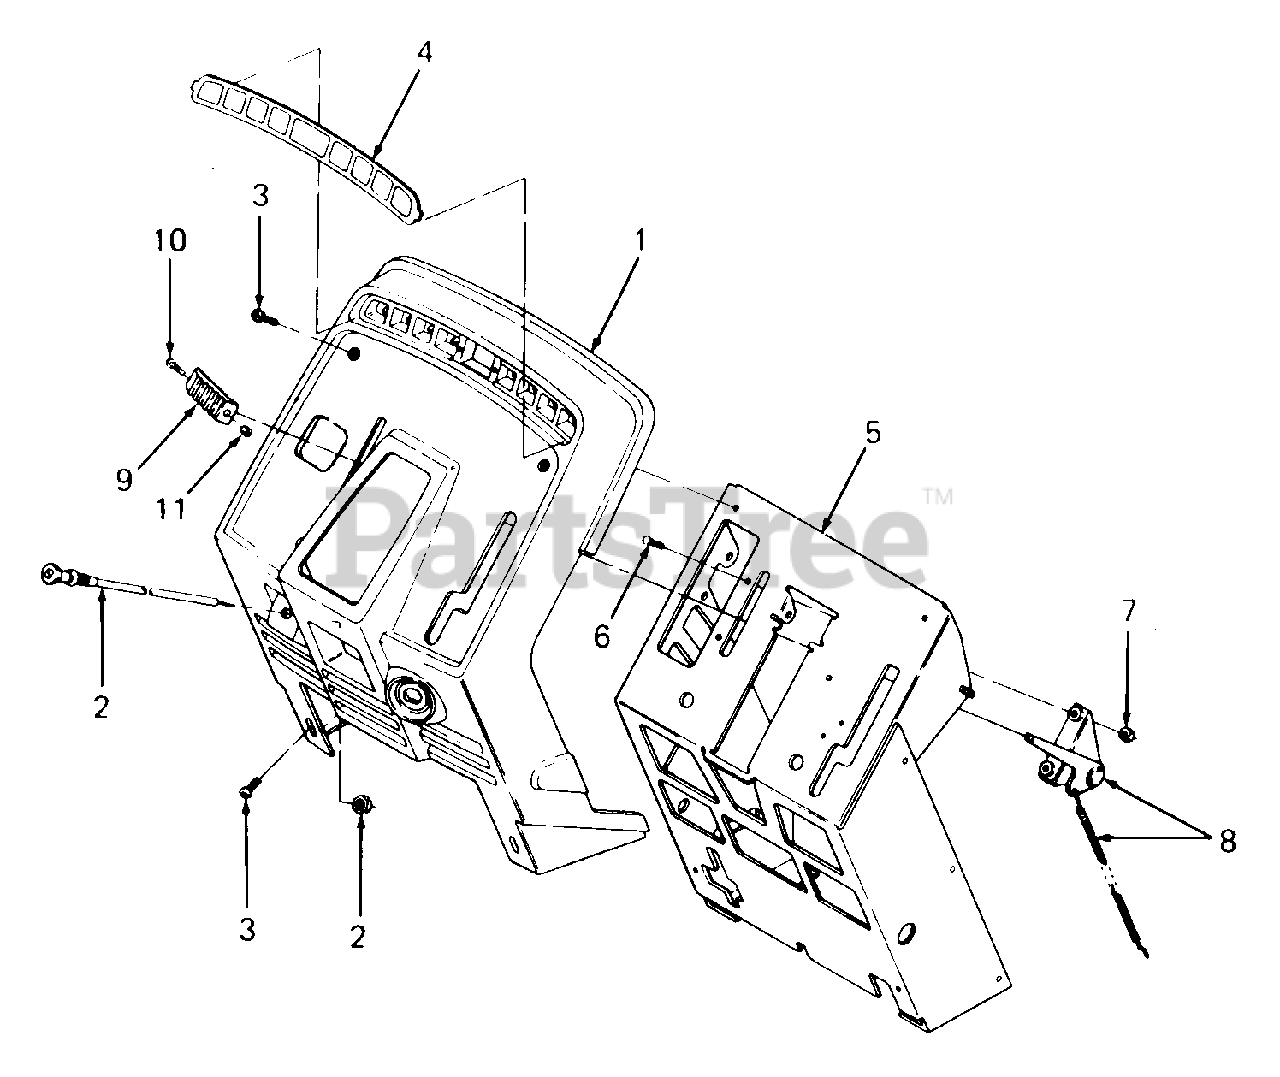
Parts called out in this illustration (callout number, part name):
1	Panel, Instrument
2	Choke Cable w/Nut
3	Screw, Pan Hd Cutting, #10-24 x .75 Lg
4	Label, Dash
7	Nut, Hex Keps, #10-32
8	Control, Throttle
9	Knob, Throttle
10	Screw, Cross Rec Truss Hd, #8-32 x .38 Lg
11	Nut, 8-32
